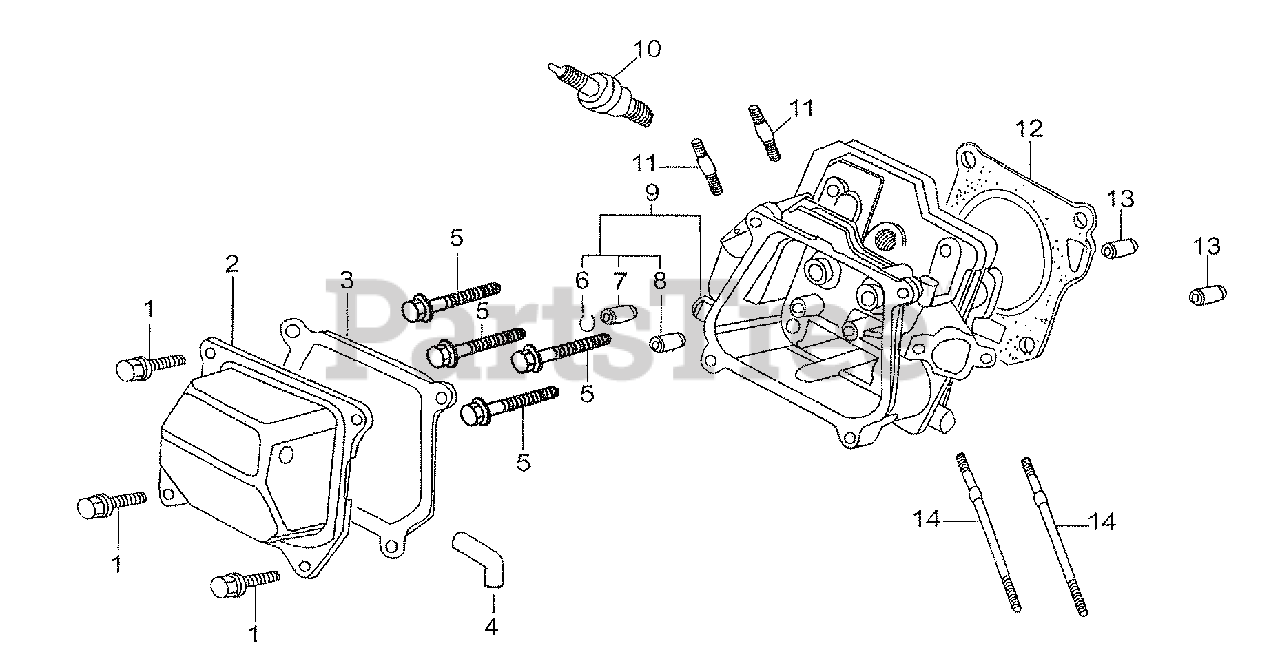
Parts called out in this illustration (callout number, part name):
1	BOLT, FLANGE, 6X12
2	COVER COMP, HEAD(BLACK)
3	GASKET, HEAD COVER
4	TUBE, BREATHER(ARC)
5	BOLT, FLANGE, 8X60
6	CLIP, VALVE GUIDE
7	GUIDE, EXH. VALVE
8	GUIDE, INTAKE VALVE
9	HEAD ASSY., CYLN
10	SPARK PLUG F6TC
11	BOLT, STUD 8X35
12	GASKET, CYLINDER HEAD
13	DOWEL PIN, 10X16
14	BOLT, STUD, 6X90
